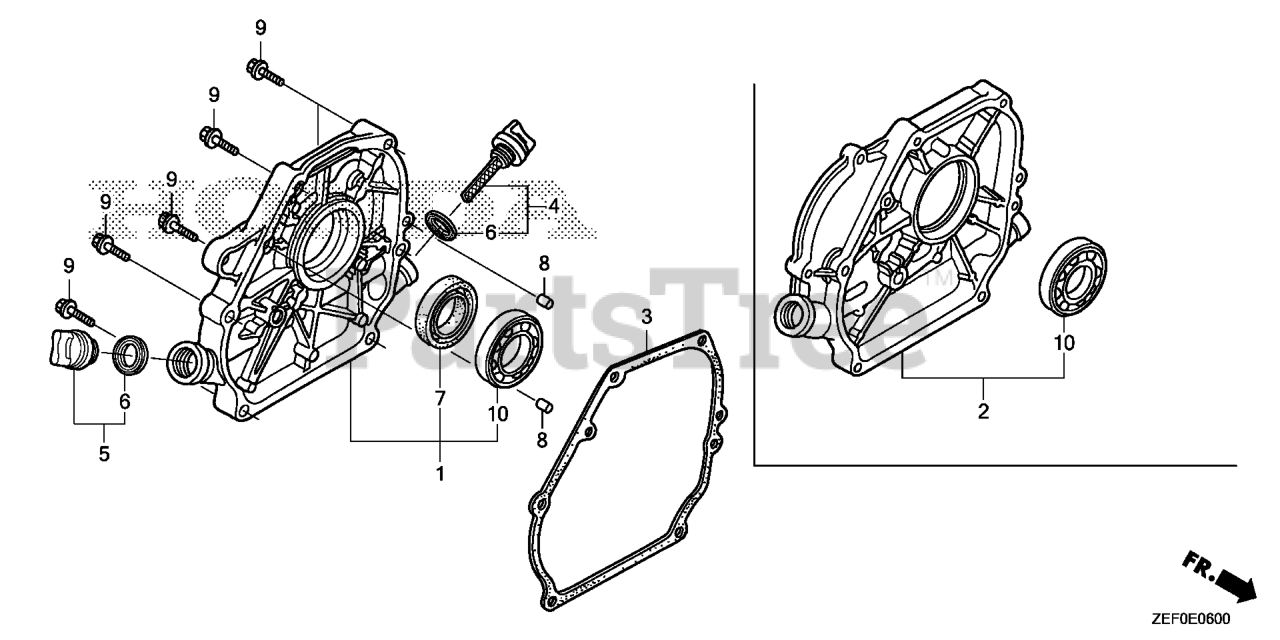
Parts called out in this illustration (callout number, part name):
1	COVER ASSY., CRANKCASE
3	GASKET, CASE COVER (NON-ASBESTOS)
4	CAP ASSY., OIL FILLER
5	CAP ASSY., OIL FILLER
6	GASKET, OIL FILLER CAP
7	OIL SEAL (25X41X6)
7	OIL SEAL (25X41X6) (ARAI) (NOT AVAILABLE)
8	PIN A, DOWEL (8X14)
9	BOLT, FLANGE (8X32)
10	BEARING, RADIAL BALL (6205)
